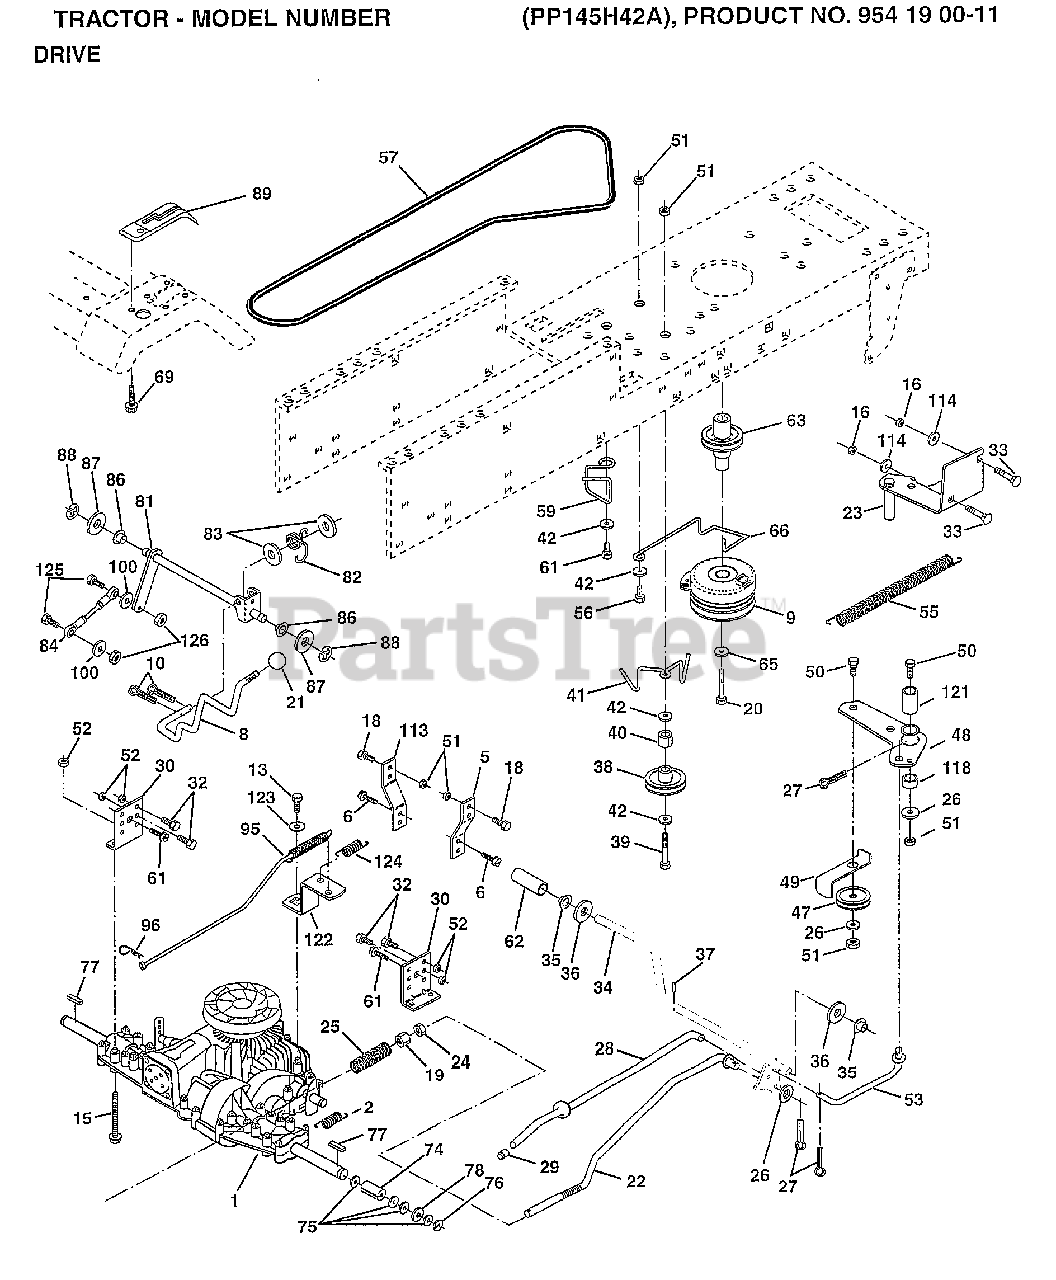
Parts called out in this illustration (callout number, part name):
2	SPRING.BRAKE.RETU
5	STRAP TORQUE
6	SCREW
8	ROD SHIFT FEND LT
9	CLUTCH.ELECT.EVX.
10	PIN COTTER 1/8
13	BOLT.1/4-28.W/PAT
15	BOLT.HX.FLG.5/16
16	NUT
18	BOLT
19	NUT
20	BOLT.7/16-20X4.25
21	KNOB.DUCKHEAD.1/2
22	BRAKE ROD
23	BRACKET.CLUT.MTG.
24	NUT
25	SPRING ROD LT
26	WASHER
27	COTTER PIN
28	ROD.BRAKE.PARK.LT
29	PLUNGER CAP T
30	TRANSAXLE MTG BKT
32	BOLT
33	BOLT
34	SHAFT ASM-PEDAL F
35	NYLON BEARING
36	WASHER LT
38	PULLEY.IDLER.FLAT
39	BOLT
40	SPACER T
42	WASHER
48	BELLCRANK ASM
49	RETAIN BELT
53	"LINK, CLUTCH T"
55	"SPRING, RETURN LT"
57	"V-BELT,GRD DRIVE"
59	KEEPER BELT CNTSP
61	SCREW
62	PEDAL COVER T
63	PULLEY.CLUTCH.EVX
65	LOCKWASHER
66	KEEPER-BELT
69	SCREW HEXWSH H-L
74	"SPACER AXLE,PVST"
75	WASHER
76	E-RING LT
77	SQUARE KEY
78	WASHER
81	SHAFT ASM CROSS
82	"SPRING,TORSION"
83	WASHER
84	ROD TIE
86	BUSHING
87	WASHER D
88	KLIP RING
95	ROAD ASM BYPASS
96	RETAINER M
100	WASHER M
113	"STRAP,TORQUE"
114	WASHER
118	SPACER-BELLCRANK
121	NYLINER-CLUTCHING
122	"PLATE-BYPASS,PVST"
123	WASHER
124	SPRING RETURN
